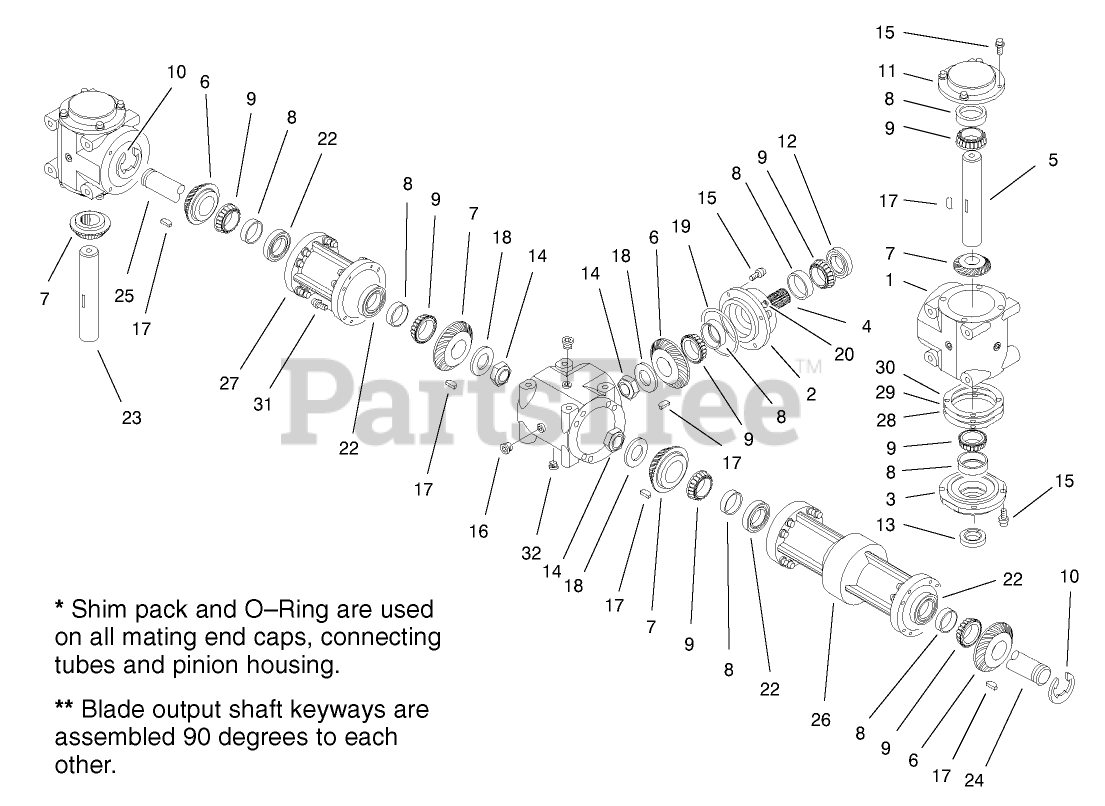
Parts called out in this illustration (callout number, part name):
2	HOUSING - PINION
3	CAP-END, OPEN
4	SHAFT - INPUT, SPLINED
5	Shaft-Cross, A/D
6	GEAR - 27 TOOTH
7	GEAR - 29 TOOTH
8	Bearing-Cup
9	Bearing-Cone
10	CLIP-RETAINING
11	CAP-END, CLOSED
13	SEAL
14	NUT-JAM
17	KEY-WOODRUFF
18	WASHER
19	O-RING
23	Shaft-Cross, B/C
24	SHAFT - CONNECTING, LONG
25	SHAFT - CONNECTING, SHORT
26	FLANGE - CONNECTING, LONG
27	FLANGE - CONNECTING, SHORT
28	SHIM-BROWN, .010IN
29	SHIM-BLUE, .005IN
30	SHIM-GREEN, .003IN
32	PLUG-MAGNETIC
